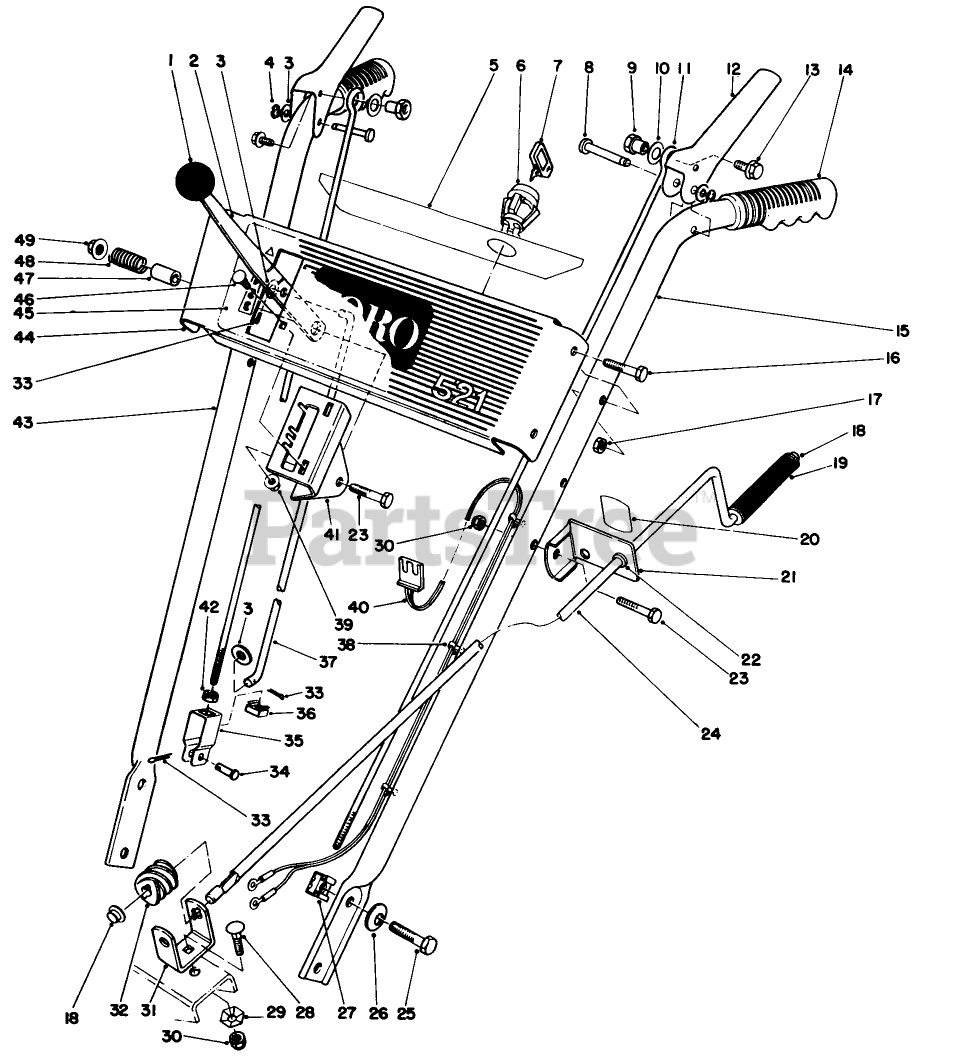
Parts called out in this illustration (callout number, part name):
3	WASHER-PLAIN
4	RING-CLIP
6	SWITCH
7	KEY-IGNITION
8	PIN-LEVER, CONTROL
9	POST-MOUNTING, LINKAGE
10	WASHER-FLAT
11	LINK-UPPER
12	HANDLE-CONTROL
13	SCREW-HHF
15	LEFT HANDLE
16	SCREW-HH
17	NUT-LOCK, NI
18	NUT-PUSH
20	DECAL-CHUTE DIRECTION
23	SCREW-HH
24	ROD-CONTROL, CHUTE
25	SCREW-HH
26	WASHER-BELLEVILLE
28	BOLT-CARR
29	WASHER-LOCK
30	NUT-LOCK, NI
31	BRACKET-WORM
32	GEAR-WORM, CHUTE
33	PIN-COTTER
34	PIN-CLEVIS
35	CLEVIS
36	NUT-RETAINED
37	ROD-SELECTOR, SPEED
38	WIRE MOUNT
39	NUT-HF
42	NUT-JAM
44	ESCUTCHEON PLT *B
47	SPACER
48	SPRING
49	NUT-HF
